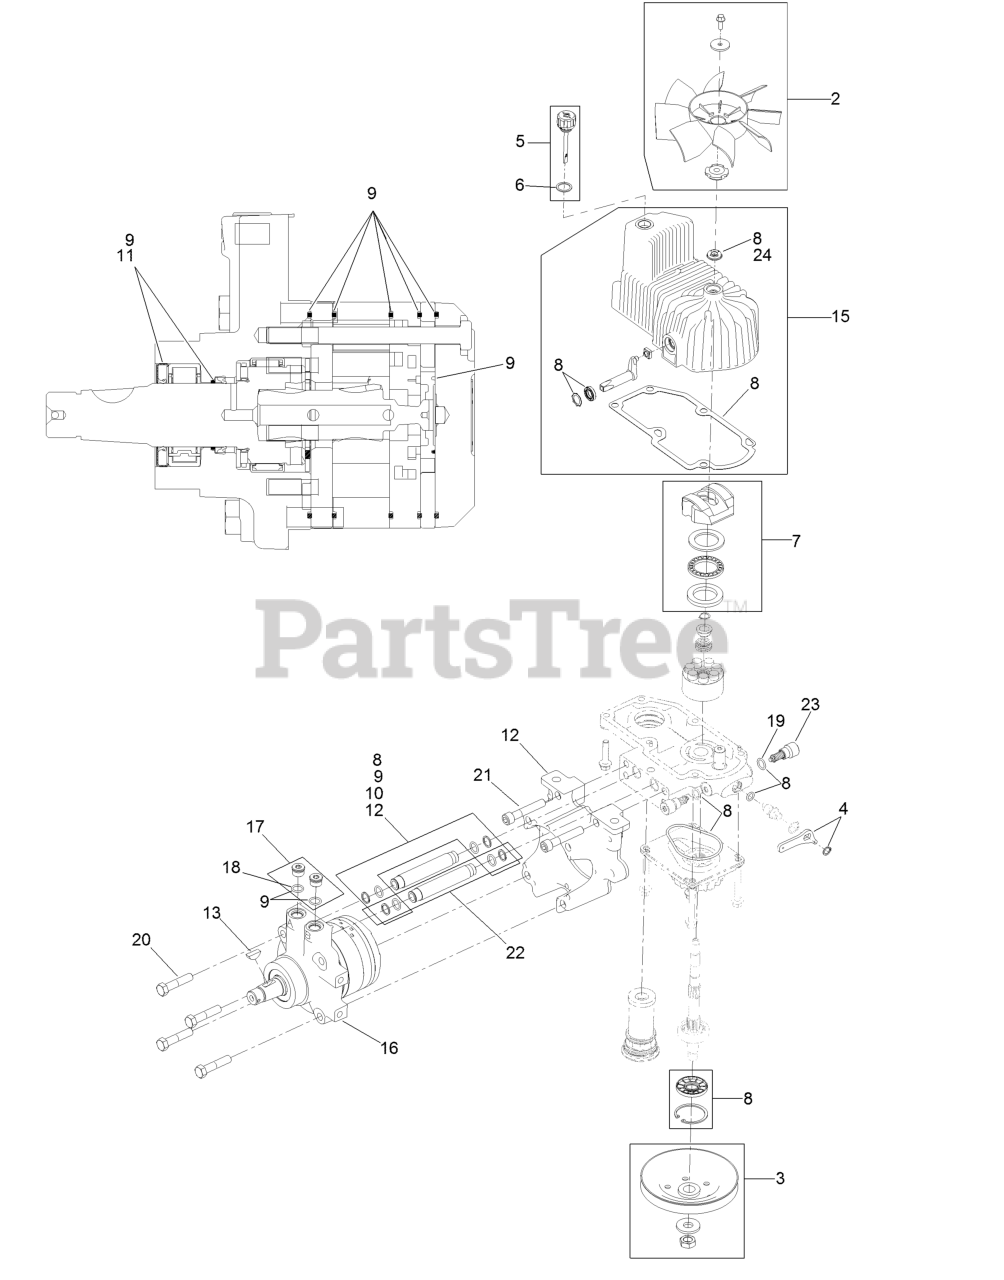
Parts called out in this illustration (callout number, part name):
2	Fan Kit
3	Pulley Kit
4	Handle-Bypass Valve, Hydro
5	Dipstick-Hydro W/Gasket
6	Gasket-Dipstick, Hydro
7	Swash Block Kit
8	Pump Seal Kit
9	Motor Seal Kit
10	Tube Seal Kit
11	Output Shaft Seal Kit
12	Nose Cup-Uht
13	Key-Woodruff
15	Housing-LH
16	Motor-Hydraulic LH 240Cc
17	Magnetic Plugs Service Kit
19	O-Ring-Check Valve
20	Screw HH
21	Screw-HSH
22	Hydraulic Tube Kit
23	Shock Valve, 12Cc Hydro
24	Seal-Fan Drive
99	Puller-Pulley
99	Flow Test Kit
